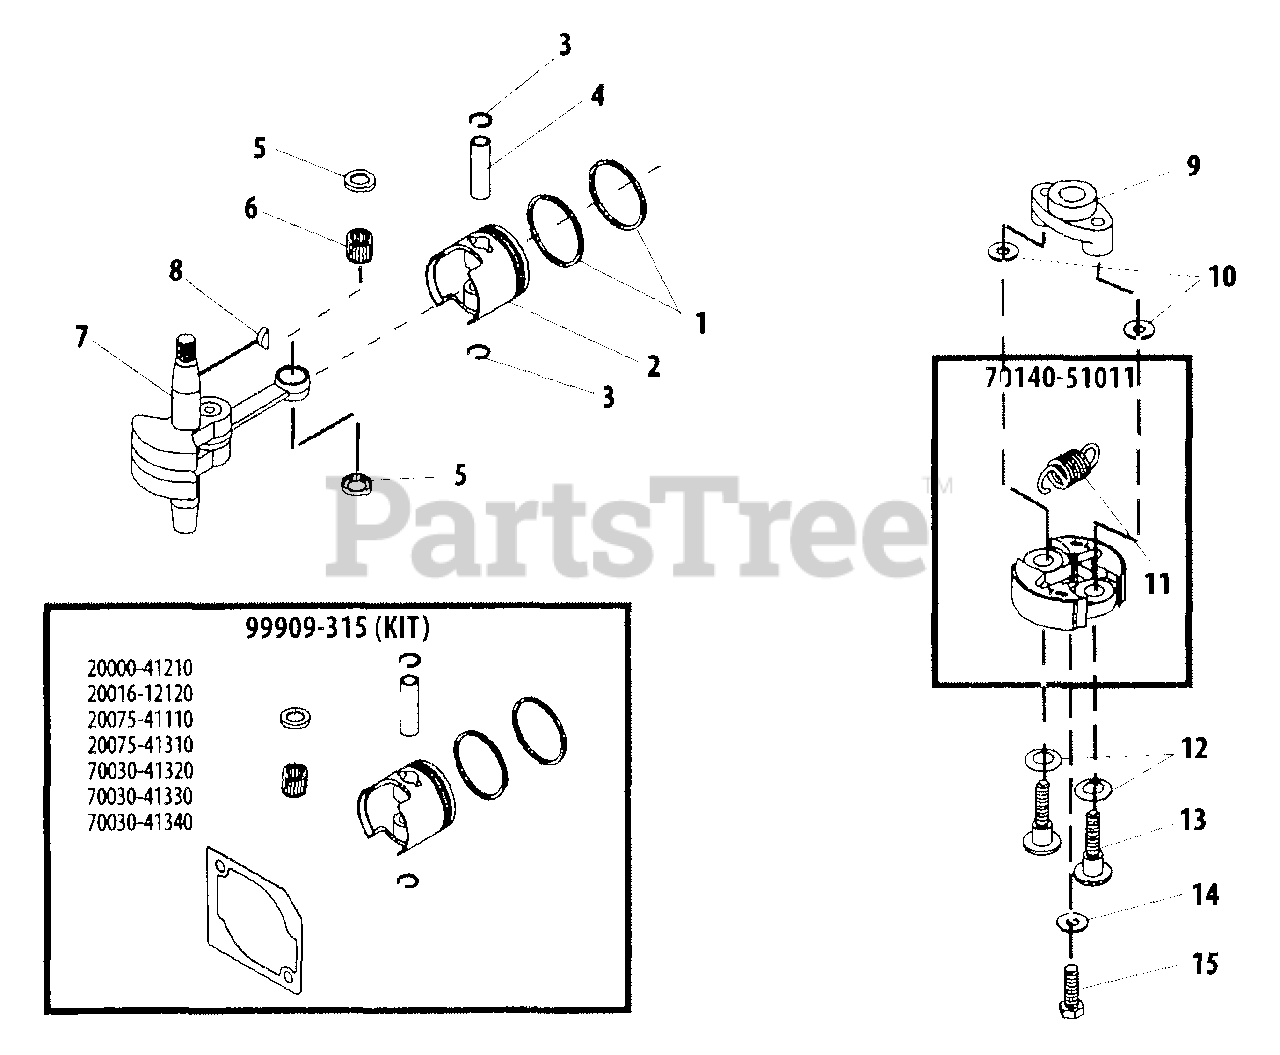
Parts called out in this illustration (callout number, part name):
1	RING, PISTON
2	PISTON
3	RING, RETAINING
4	PIN, PISTON
5	WASHER, THRUST
6	BEARING, NEEDLE
7	CRANKSHAFT ASSY
8	KEY - 3X10
9	HUB, CLUTCH
10	WASHER - 6
11	SPRING, CLUTCH
12	WASHER - SPRING
13	BOLT, CLUTCH
14	WASHER - 6
15	SCREW - 6X18
70140-51011	CLUTCH SHOE ASSY
99909-315	PISTON ASSY
